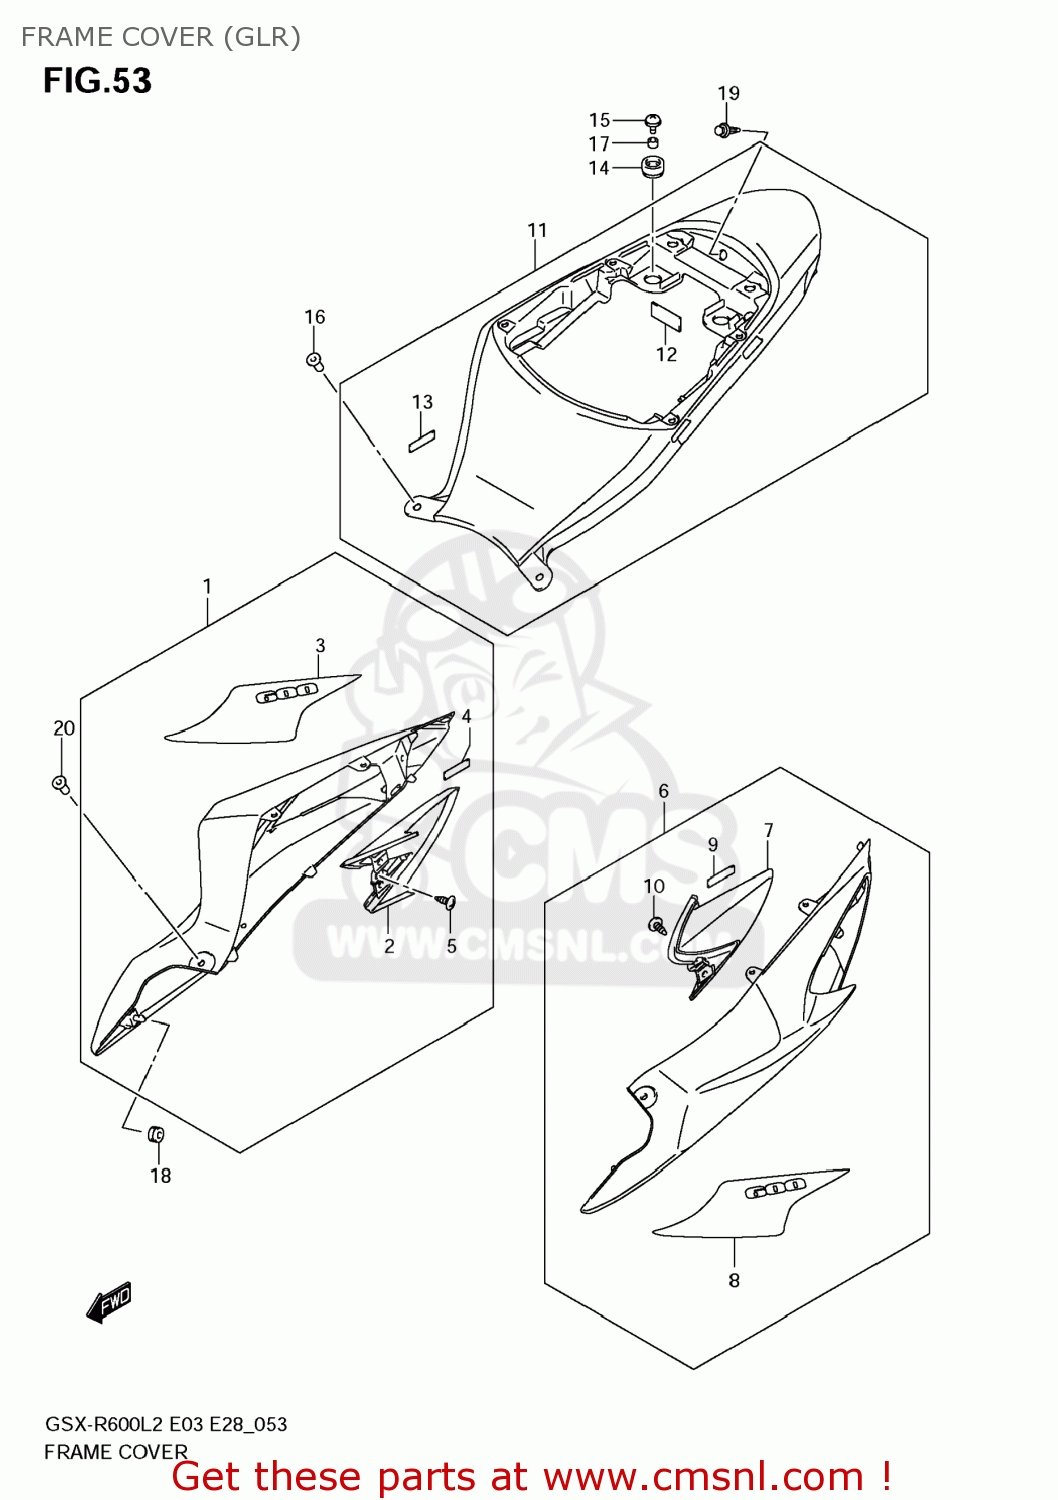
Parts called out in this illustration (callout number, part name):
1	COVER ASSY,FRAME,R(WHITE)
2	COVER,FRAME RR,R
3	TAPE,FRAME COVER,R
4	TAPE(6X25X0.13)
5	SCREW
6	COVER ASSY,FRAME,L(WHITE)
7	COVER,FRAME RR,L
8	TAPE,FRAME COVER,L
9	TAPE(6X25X0.13)
10	SCREW
11	COVER ASSY,FRAME CTR
12	CUSHION
13	TAPE(6X25X0.13)
14	CUSHION,FRAME COVER RR
15	SCREW(6X16)
16	NUT
17	SPACER(6.5X10X7)
18	CUSHION
19	CLIP(BLACK)
20	SCREW
